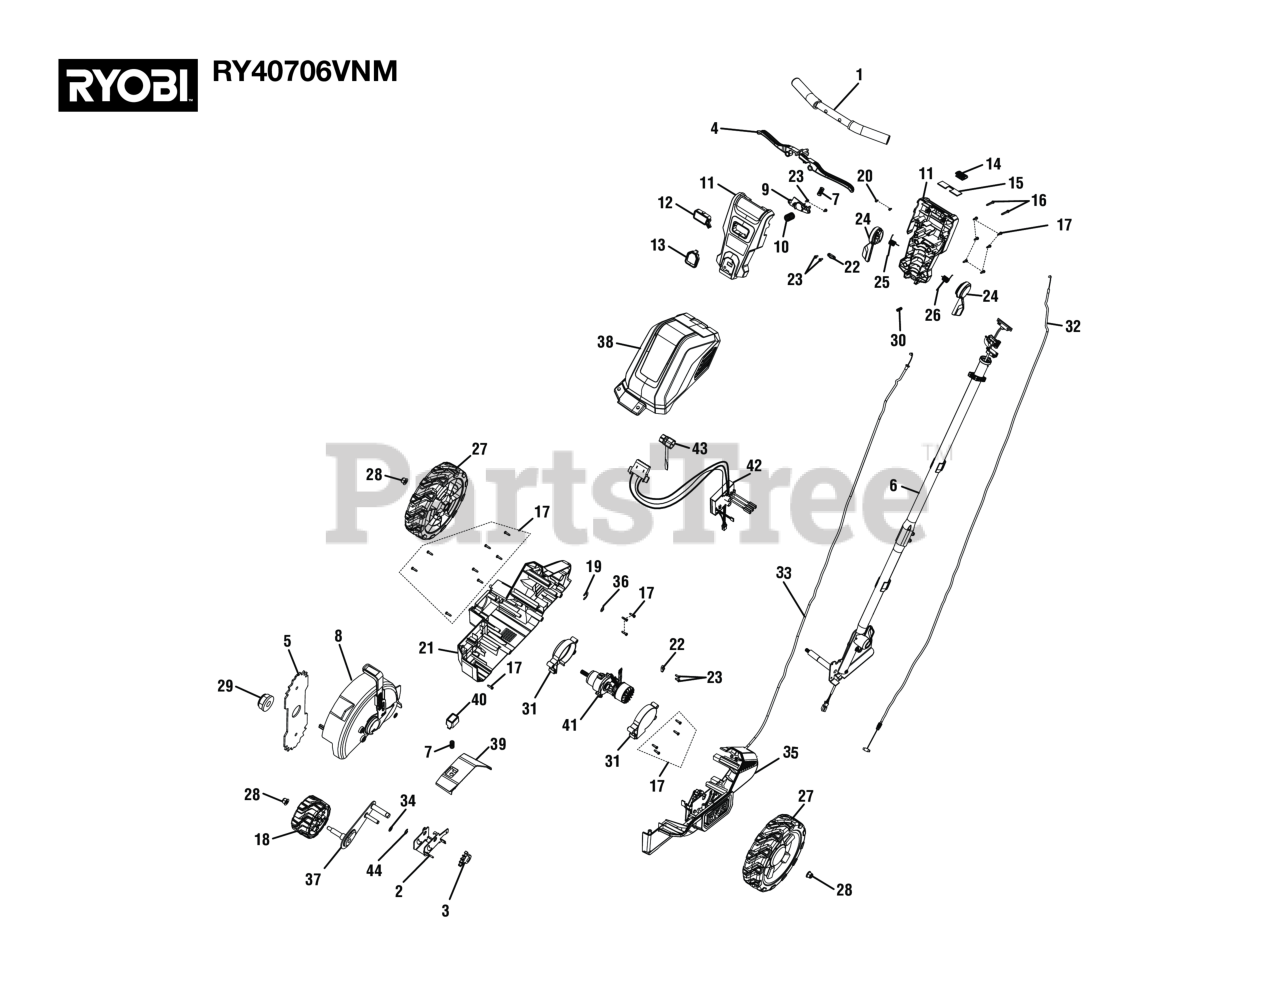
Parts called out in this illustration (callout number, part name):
1	Handle Assembly
2	Front Wheel Adjustor Bracket
3	Spur Gear
4	Trigger Assembly
5	Edger Blade
6	Tube Assembly (Inc. Labels)
7	Compression Spring
8	Blade Guard Assembly
9	Spring Holder
10	Safety Button Spring
11	Handle Housing Assembly (Inc. Labels)
12	Lock Button
13	Rotating Handle Button Assembly (Inc. Labels)
14	Thumb Pad
15	Dust Shield
16	Screw (M4-18 x 30 mm, T15 Torx Soc. Hd.)
17	Screw (M4 x 14 mm, T15 Torx Pan Hd.))
18	Front Wheel Assembly
20	Screw (M3 x 8 mm, Pan Hd., Pan Hd)
21	Right Base Housing Assembly (Inc. Labels)
22	Cord Clamp
23	ST SCREW BH BM X 10
24	Height Adjustment Lever
25	Lever Spring (Right)
26	Lever Spring (Left)
27	8 in. Rear Wheel Assembly
28	Flange Lock Nut (M8 x 1.25 mm)
29	Flange Nut (M8)
31	Motor Volute Assembly
32	Cable (Front Wheel Adjustor)
33	Cable (Rear Wheel Height Adjustor)
35	Left Bottom Base Housing Assembly
36	RING, RETAINING
37	Front Wheel Height Adjustment Plate
38	Upper Housing Assembly (Inc. Label)
39	Button Cover
40	Blade Lock Button Assembly (Inc. Labels)
41	Motor Assembly
42	Motor Controller Assembly
43	Combination Wrench
